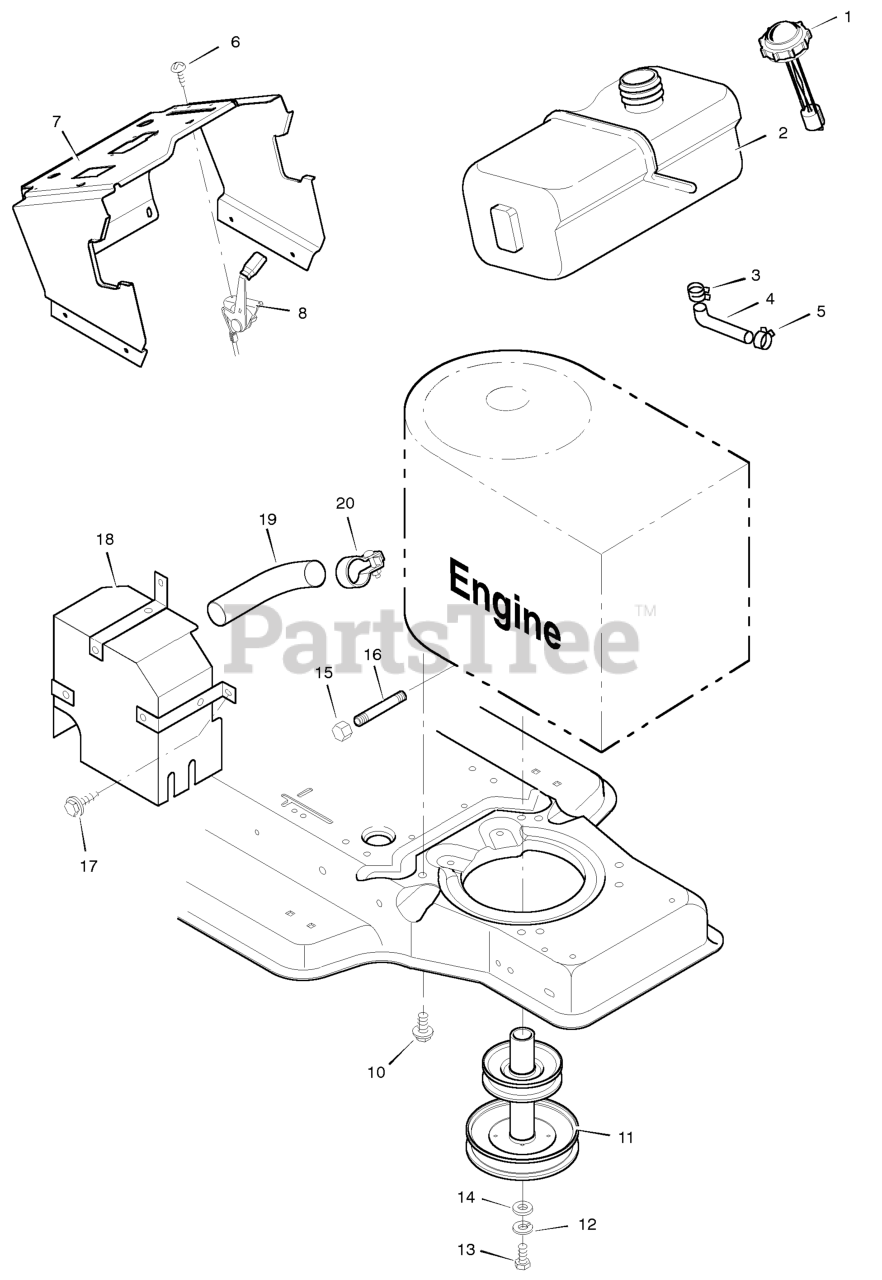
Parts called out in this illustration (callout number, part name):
1	Fuel Cap
2	Fuel Tank
3	Hose Clamp
4	Fuel Line
5	Hose Clamp
7	Support, Dash
8	Throttle Control
9	Engine *
10	Bolt, Engine Mount
11	Stack Pulley Assembly
12	Lockwasher
13	Bolt, Hex
15	Cap, Oil Drain
16	Pipe, Oil Drain
18	Shield, Heat
19	Pipe, Exhaust
